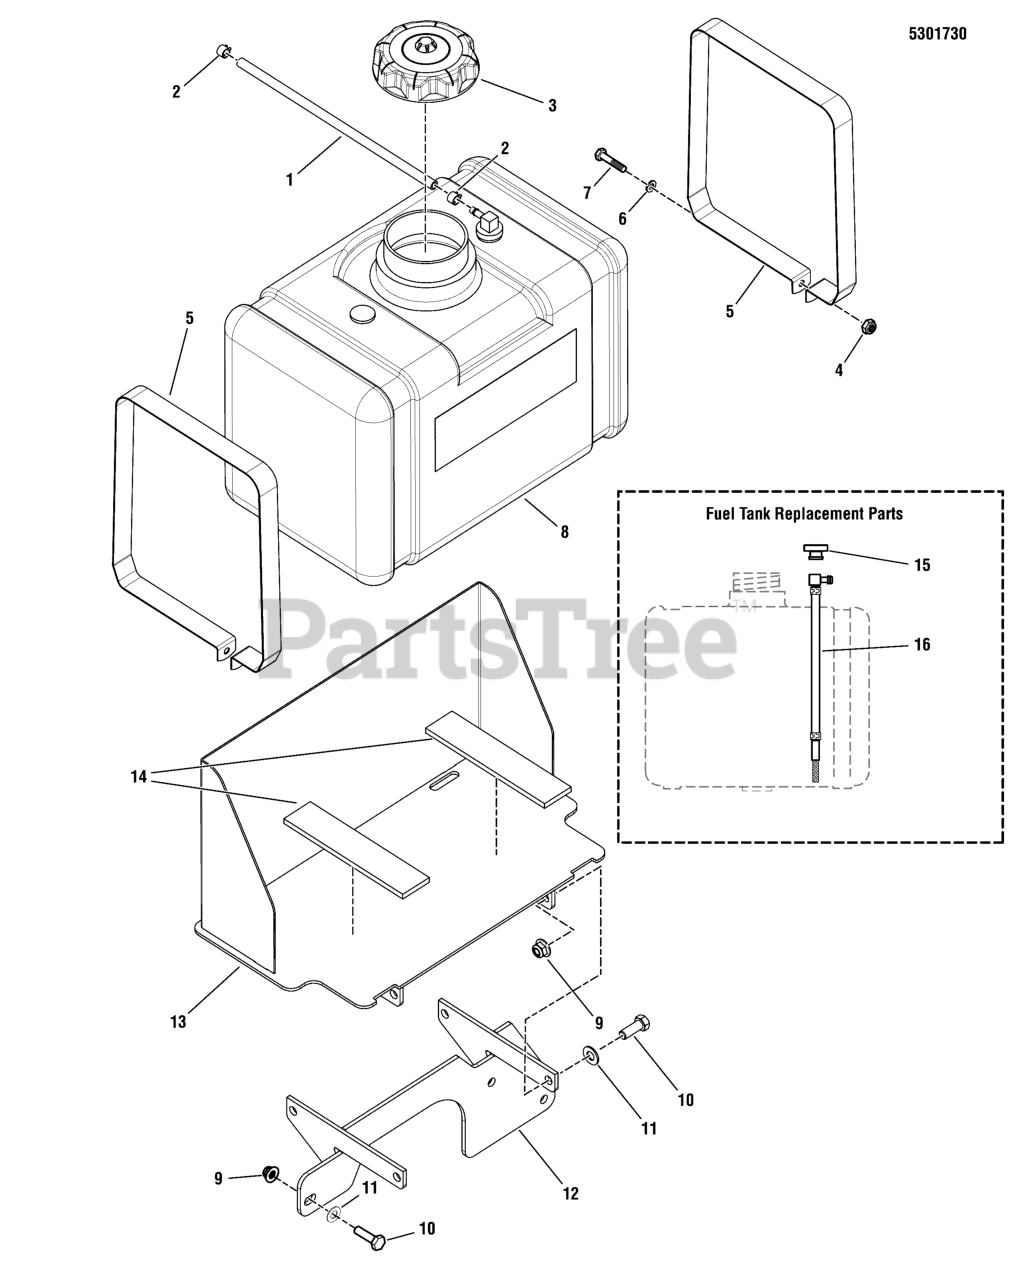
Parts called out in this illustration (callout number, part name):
1	HOSE, 1/4" FUEL, 12.00"
2	CLAMP, HOSE, EXTERNAL, 1/2 - RED
3	FUEL CAP, 3-1/2", MANAGED VENT OUT, 12"
3	CAP, GASOLINE, VENTED
4	NUT, 1/4-20 HEX NYLOCK FLANGE
5	STRAP, FUEL TANK
6	WASHER, 1/4 SAE
7	BOLT, 1/4-20 X 1-1/4, GD5
8	TANK, 5 GAL, W DROP TUBE / VENT
8	TANK, FUEL, PLASTIC, TOP DRAW, NO LOGO
9	NUT, 3/8-16 HEX NYLOCK FLANGE
10	BOLT, 3/8-16 X 1" GD5 CZ
11	WASHER, 3/8 SAE
12	WELD, LOWER FUEL TANK MNT - RED
13	WELD, TANK MOUNT, SW20-52-61 - RED
14	PAD, RUBBER MOUNT
15	KIT, BUSHING FUEL
16	HOSE, 1/4 FUEL, 25" LONG
17	GROMMET
